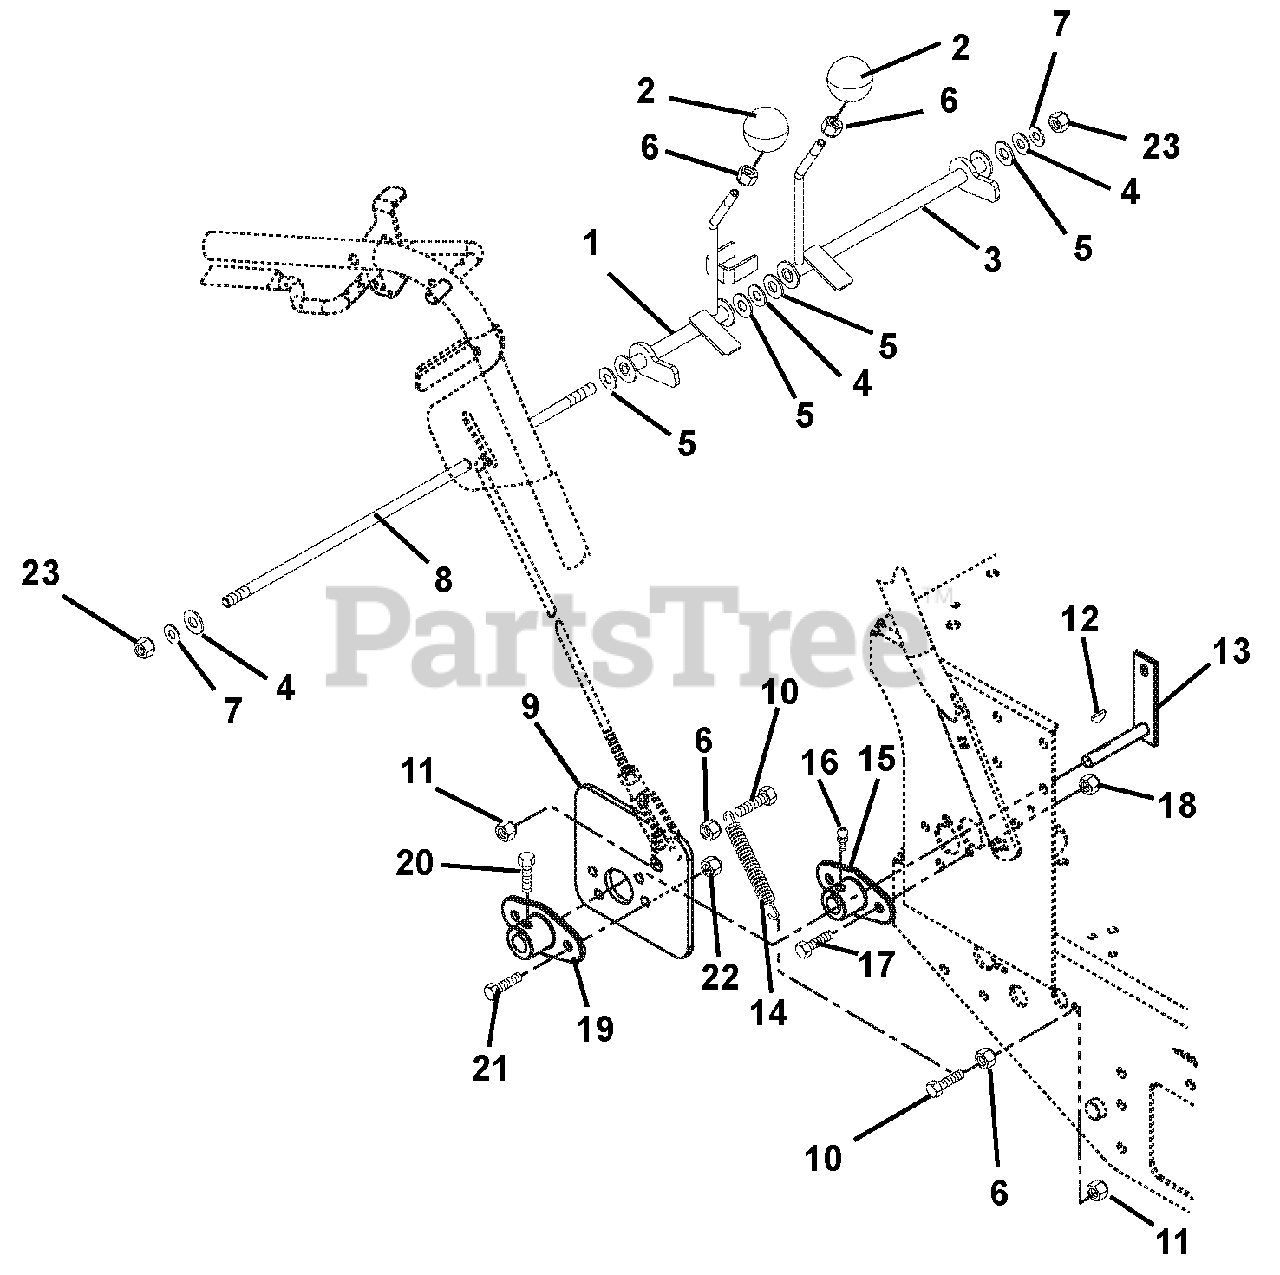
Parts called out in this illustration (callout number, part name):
1	Weldment, Right Hand Lever
2	Knob, Ball-Black 1-13/32, .375-16
3	Weldment, Left Hand Lever
4	Washer-Flat-Steel .406 x .812 x .065
5	Washer-Flat-Nylon .375 x 1.00 x .062
6	Nut-Hex .38-16
7	Washer-Locking .38 x .094 Regular
8	Rod, Speed Control
9	Plate, Speed Control
10	Bolt-Hex .38-16 x 1.50 Grade 5
11	Nut-Locking-Nylon .38-16
12	Key-Woodruff .125 x .75
13	Weldment, Pump Control Left Hand
14	Spring-Tension .105 x 1.00 x 5.0
15	Bushing, Flanged
16	Fitting-Lube .25-28 x .256
17	Bolt-Hex .31-18 x 1.00 Grade 5
18	Nut-Locking-Nylon .312-18
19	Arm, Speed Control
20	Bolt-Hex .25-20 x .50 Grade 5
21	Bolt-Hex .25-20 x .75 Grade 5
22	Nut-Locking-Nylon .25-20
23	Nut-Hex .375-24 Grade 2
